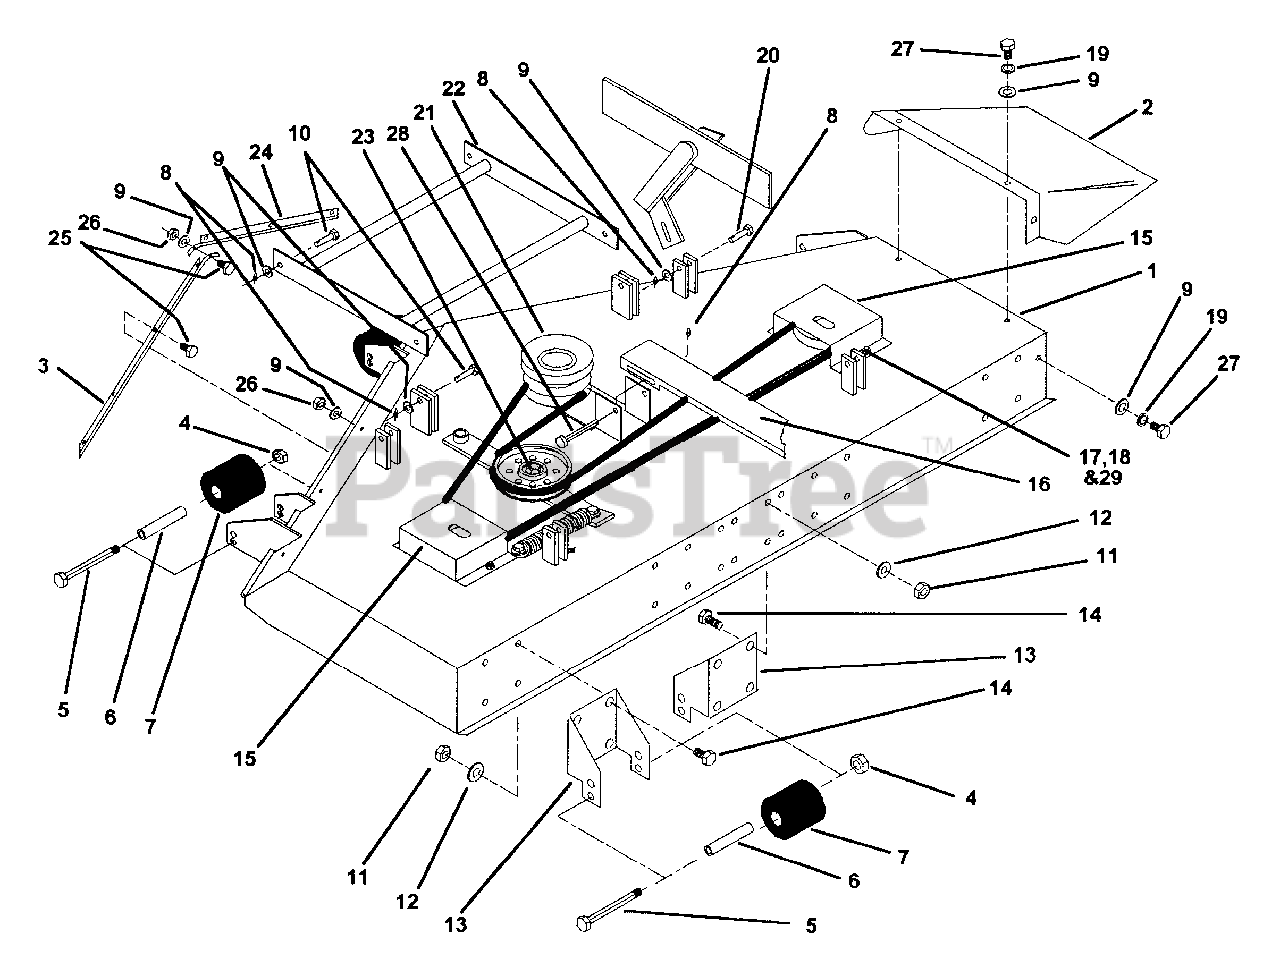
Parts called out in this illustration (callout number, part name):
1	48" DECK, WELDMENT
2	48" DECK CHUTE ASSEMBLY
3	LIP BAFFLE, 48" L. H.
4	LOCKNUT, 3/8-16, .218 THICK
5	CAP SCREW, 3/8-16 X 5" GR. 5
6	ROLLER SPACER BUSHING
7	ROLLER
8	COTTER RUE RING, 5/16-3/8 PIN
9	WASHER FLAT STD. 5/16"
10	CLEVIS PIN, 5/16 X 1-1/4" LONG
11	NUT, 3/8-16 NYLOC
12	WASHER, FLAT STD. 3/8"
13	REAR ANTI-SCALPER BRACKET
14	BOLT, 3/8-16 X 7/8" GR. 5
15	PULLEY COVER, LOW HEIGHT
16	DOUBLE IDLER CHANNEL ASSEMBLY
17	BOLT, 1/4-20 X 3/4" GR. 5
18	LOCK WASHER, 1/4" SPLIT SPRING
19	LOCK WASHER, 5/16" SPLIT SPRING
20	CLEVIS PIN, 5/16 X 1-1/2" LONG
21	SPINDLE ASSEMBLY
22	DRAG BAR WELDMENT
23	SINGLE IDLER PARTS
24	LIP BAFFLE, 48" DECK, R.H.
25	BOLT, 5/16-18 X 3/4" CARRIAGE
26	NUT, 5/16-18 NYLOC
27	BOLT, 5/16-18 X 3/4" GR. 5
28	CLEVIS PIN, 3/8 X 2-3/4 O.A.L.
29	WASHER, FLAT STD, STEEL, 1/4"
